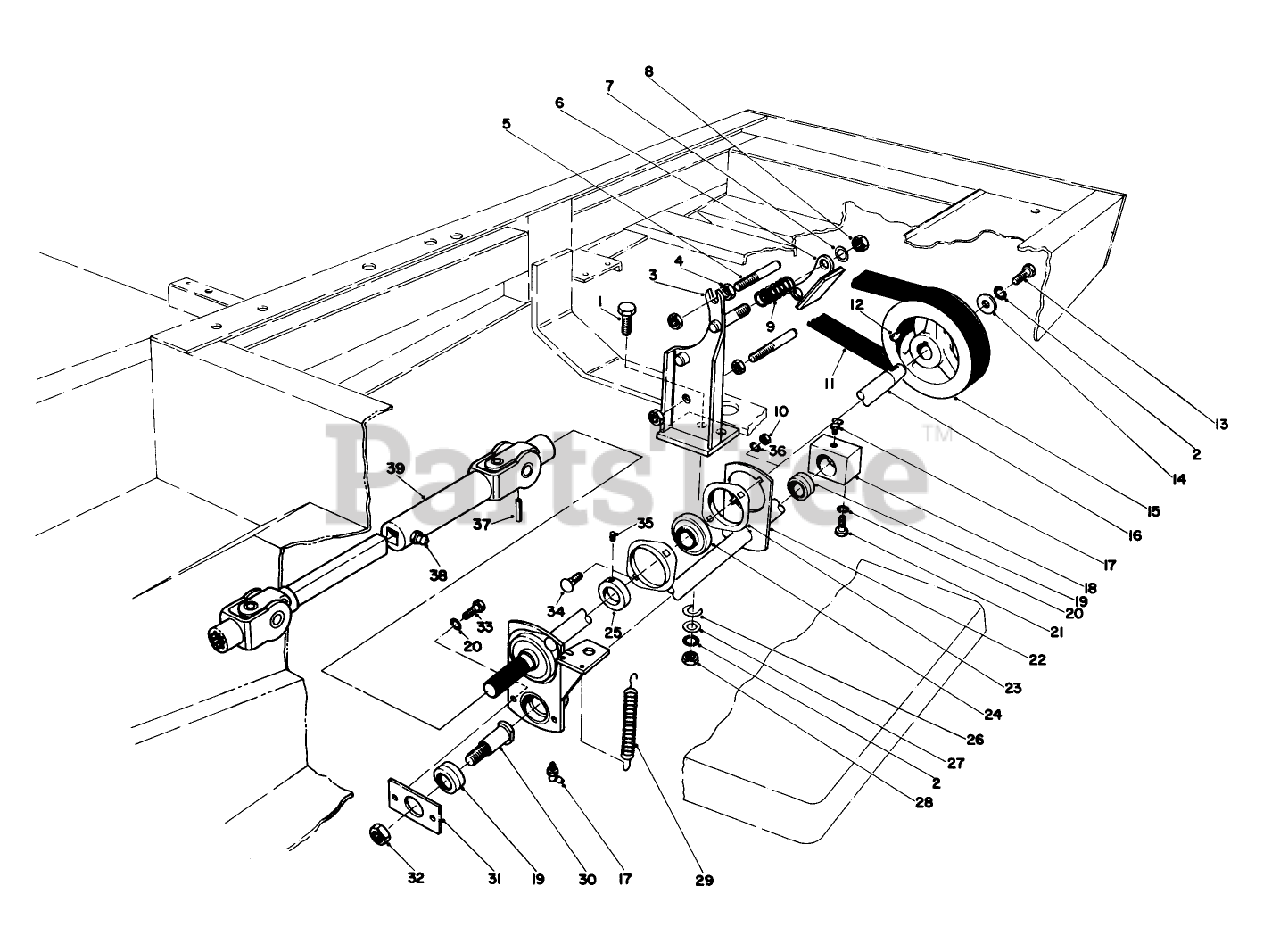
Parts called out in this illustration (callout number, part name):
1	SCREW-HH
2	WASHER-LOCK
3	PTO BRAKE BRKT WA BO
4	NUT-HHF, WHIZ
5	PTO BELT GUIDE
6	PTO BRAKE SHOE/LINING
7	WASHER-FLAT
8	NUT-LOCK, NI
9	COMP SPRING O
10	NUT-HEX
11	V-BELT, TORQUE TEAM
12	KEY-WOODRUFF
13	SCREW-HH
14	WASHER-FLAT
15	PULLEY-PTO, MACH.
16	PTO SHAFT
17	FITTING-GREASE, 90 DEG
18	BEARING HUB PP
19	BEARING
20	WASHER-LOCK
21	SCREW-HH
22	Engagement Arm
23	FLANGE
24	Bearing w/collar (Incl. Ref. #25 & 35)
25	COLLAR-LOCK, BEARING
26	SPECIAL WASHER
27	WASHER-FLAT
28	NUT-HEX
29	TENSION PTO SPRING R
30	BEARING STUD
31	BRG RETAINER
32	NUT-LOCK, NI
33	SCREW-HH
34	SCREW-CARR
35	SCREW-SET, HSH
36	WASHER-LOCK
37	PIN-ROLL
38	FITTING-GREASE
39	UNIVERSAL JOINT
